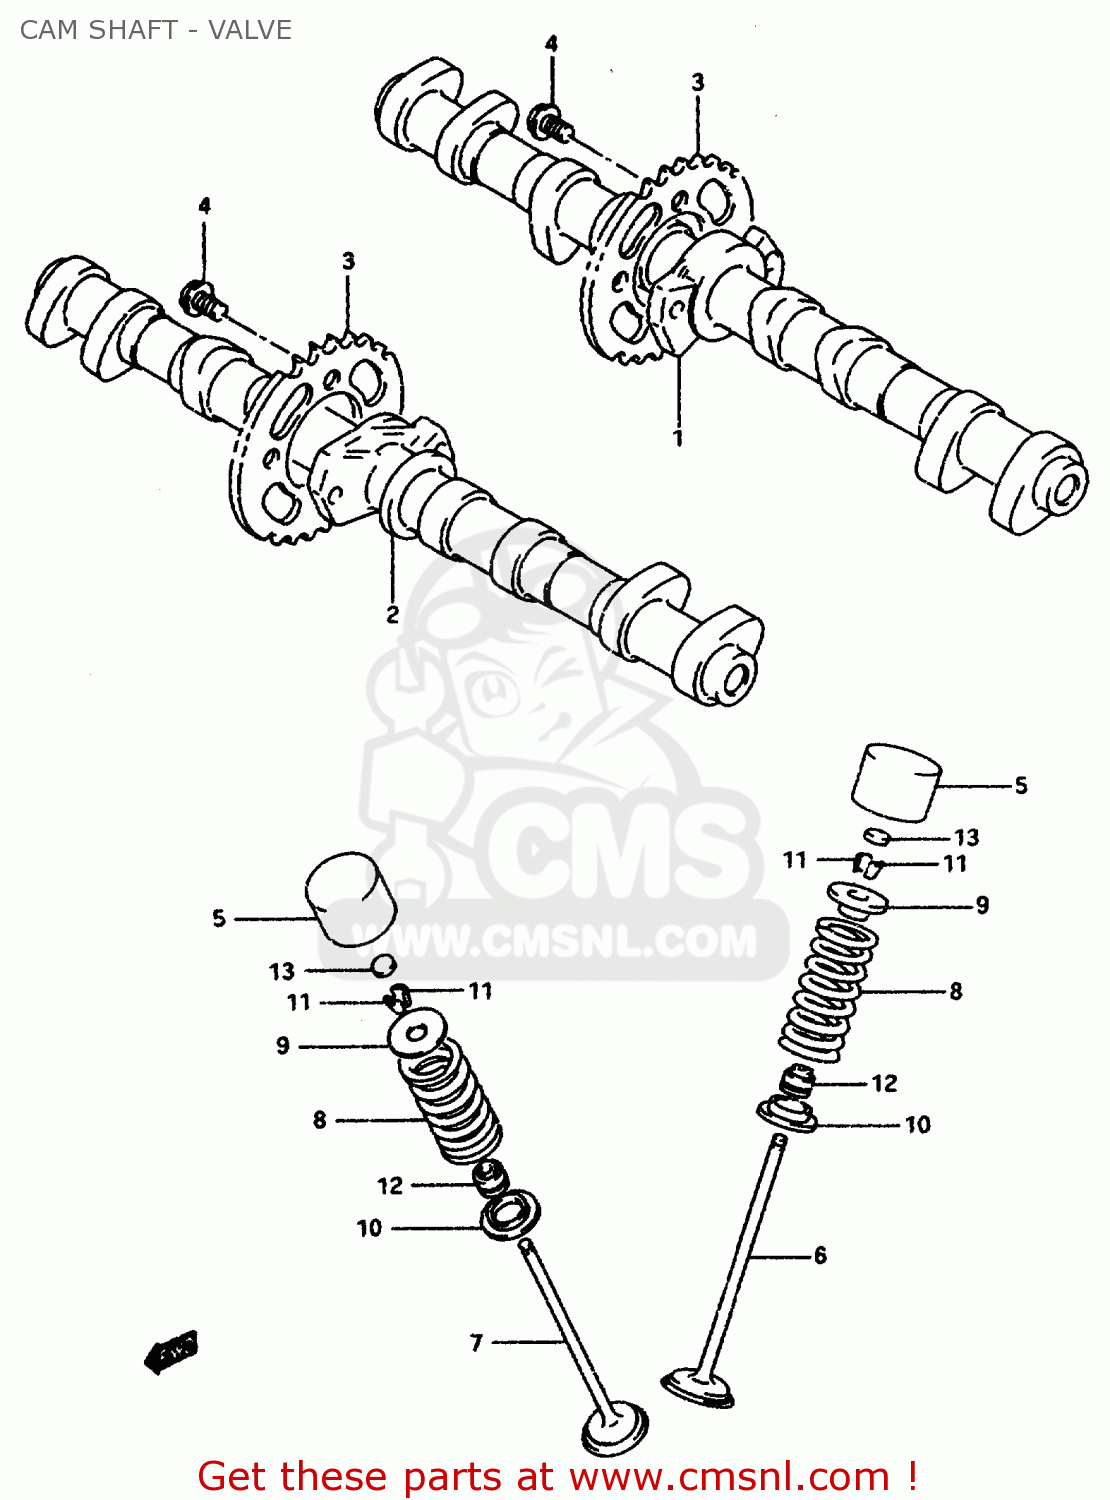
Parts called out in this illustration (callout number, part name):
1	CAMSHAFT,INTAKE
2	CAMSHAFT,EXHAUST
3	SPROCKET,CAMSHAFT
4	BOLT(7X11)
5	TAPPET
6	VALVE,INTAKE
7	VALVE,EXHAUST
8	SPRING,VALVE
9	RETAINER,VALVE SPRING
10	SEAT,VALVE SPRING
11	COTTER VALVE
12	SEAL,OIL(4.5X10X8)
13	SHIM,TAPPET
15	CASE,TAPPET SHIM
